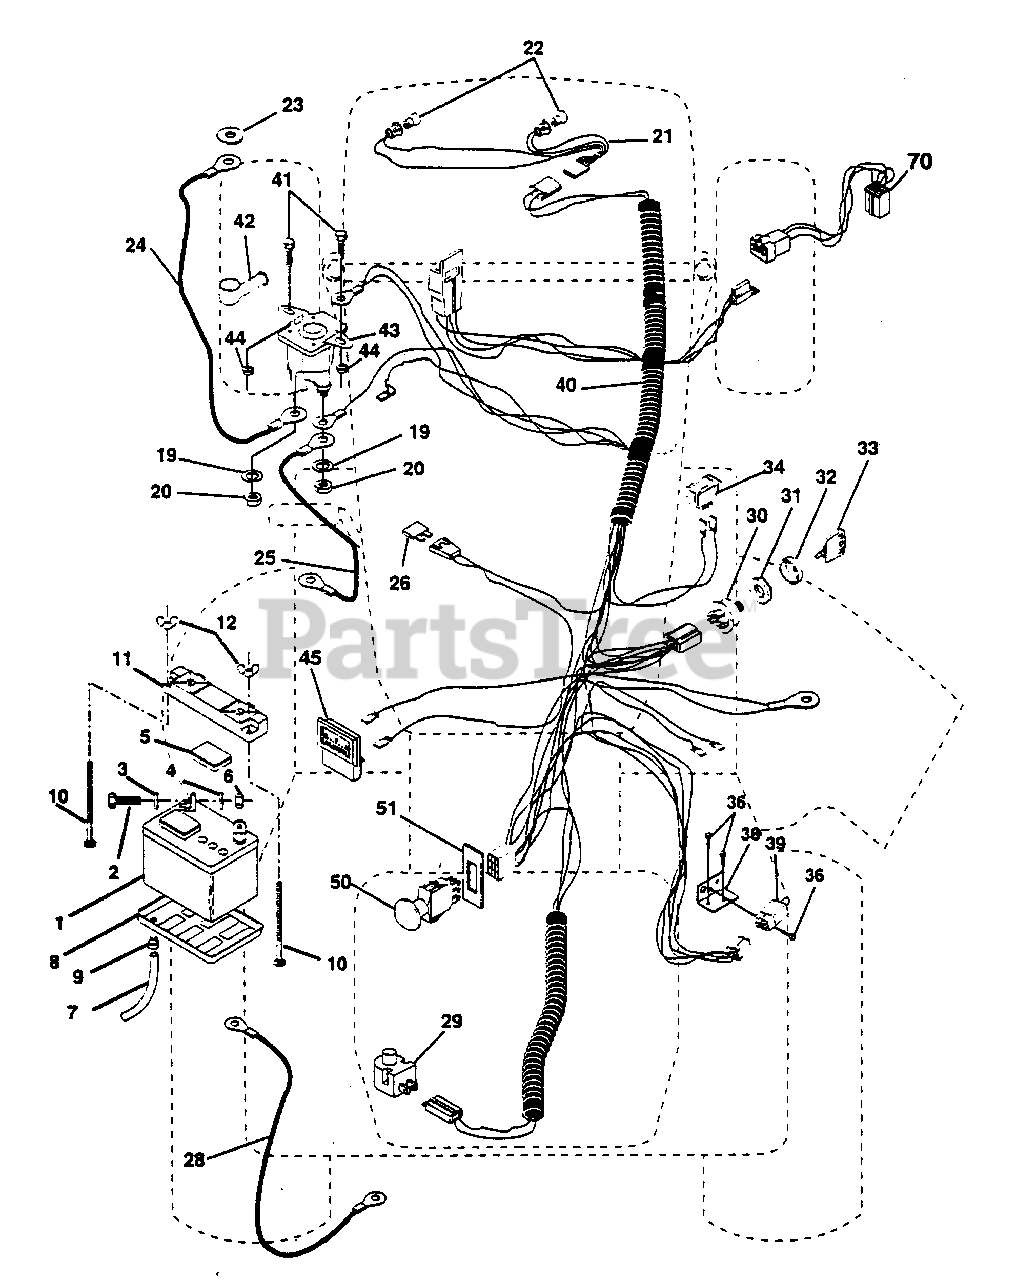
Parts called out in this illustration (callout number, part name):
1	Battery (AYP part number)
2	Bolt, Hex Head 1/4-20 x 3/4 (AYP part number)
3	Washer 9/32 x 5/8 x 16 Gauge (AYP part number)
4	Washer, Lock 1/4 (AYP part number)
5	Caps, Battery (AYP part number)
6	Nut, Hex 1/4-20 (AYP part number)
7	Tube, Tray, Battery (AYP part number)
8	Tray, Battery (AYP part number)
9	Clamp, Hose (AYP part number)
10	Bolt, Carriage 1/4-20 x 7-1/2 (AYP part number)
11	Guard, Terminal (AYP part number)
12	Nut, Wing 1/4-20 (AYP part number)
19	Washer, Lock 1/4 (AYP part number)
20	Nut, Hex, Jam 1/4-20 (AYP part number)
21	Harness, Socket, Light (Inc.11) (AYP part number)
22	Bulb, Light (AYP part number)
23	Washer, Lock, Internal Tooth 1/4 (AYP part number)
24	Cable, Starter, 6 Ga 11" Red (AYP part number)
25	Cable, Battery (AYP part number)
26	Fuse (AYP part number)
28	Cable, Battery (AYP part number)
29	Switch, Plunger (AYP part number)
30	Switch, Ignition (AYP part number)
31	Nut, Ignition (AYP part number)
32	Cover, Switch, Ignition (AYP part number)
33	Key, Molded (AYP part number)
34	Switch, Light (AYP part number)
36	Screw, Hex Tap #10-24 UNC (AYP part number)
38	Bracket Switch Interlock (AYP part number)
39	Switch, Interlock (4 Terminal) (AYP part number)
40	Harness, Ignition (AYP part number)
41	Bolt, Hex 1/4-20 x 1/2 Grade 5 (AYP part number)
42	Cover, Terminal (AYP part number)
43	Solenoid (AYP part number)
44	Nut, Hex, Keps 1/4-20 (AYP part number)
45	Ammeter rectangular 15 AMP (AYP part number)
50	Switch, P.T.O. (AYP part number)
51	Ring, Retainer, Pto (AYP part number)
70	Harness, Engine
